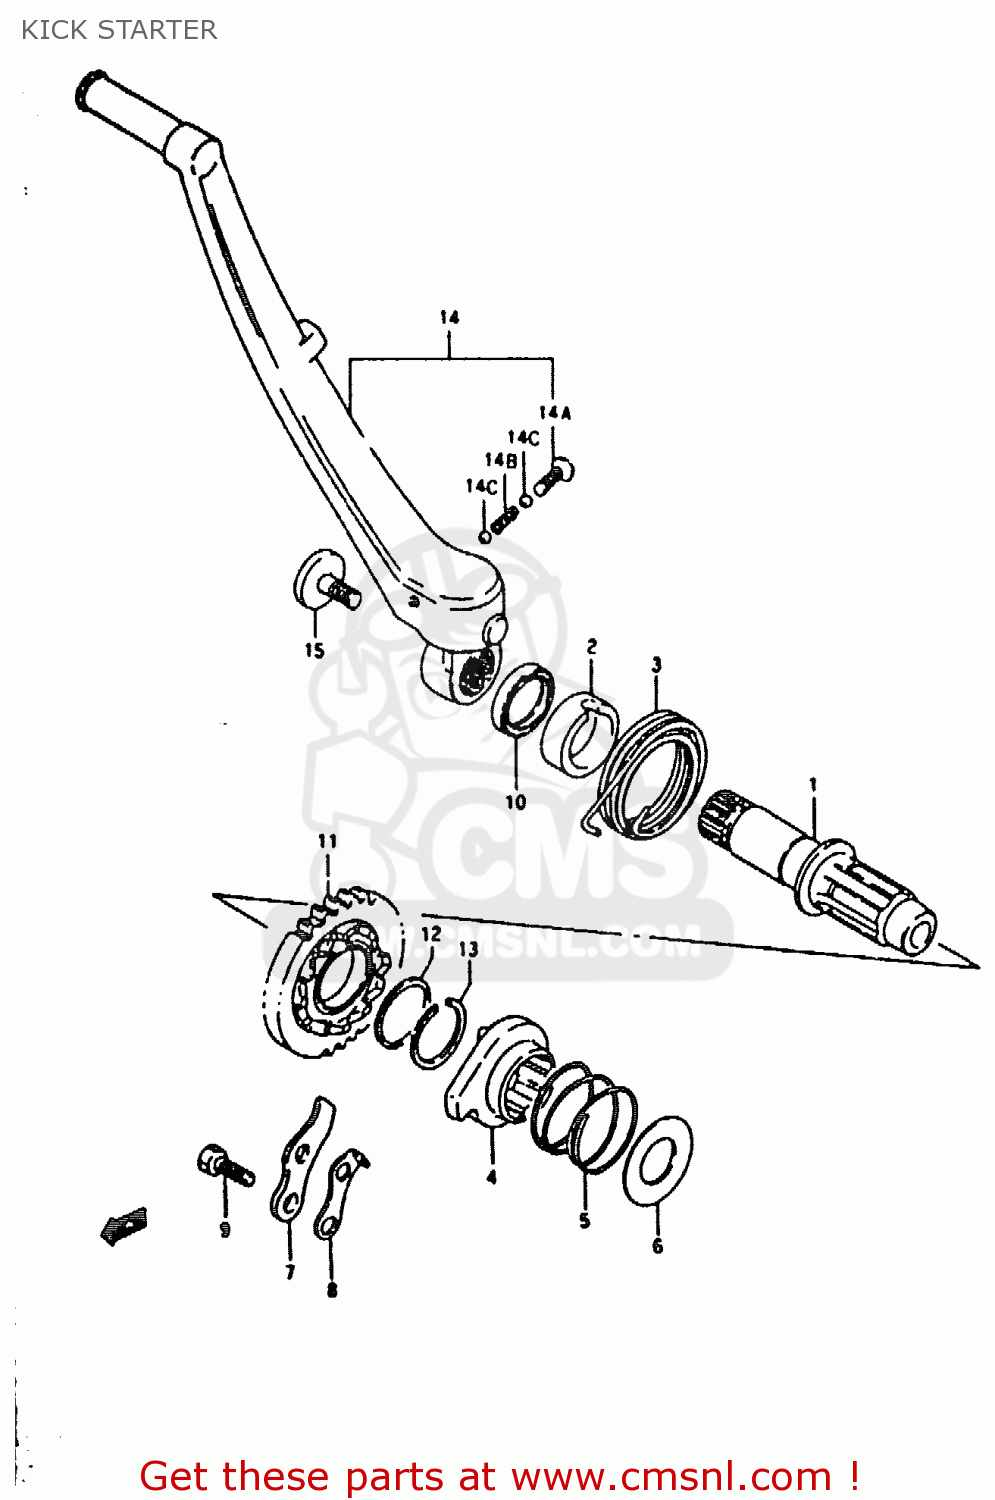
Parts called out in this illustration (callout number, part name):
1	SHAFT,KICK STARTER
2	GUIDE,KICK STARTER SHAFT
3	SPRING
4	STARTER,KICK
5	SPRING
6	WASHER
7	GUIDE,KICK STARTER
8	STOPPER,KICK STARTER
9	BOLT
10	SEAL,OIL(20X27X5)
11	GEAR,KICK STARTER DRIVE(NT:30)
12	SHIM
13	CIRCLIP
14	LEVER ASSEMBLY,KICK STARTER
14A	SCREW(6X27.5)
14B	SPRING
14C	BALL
15	BOLT(8X14)
